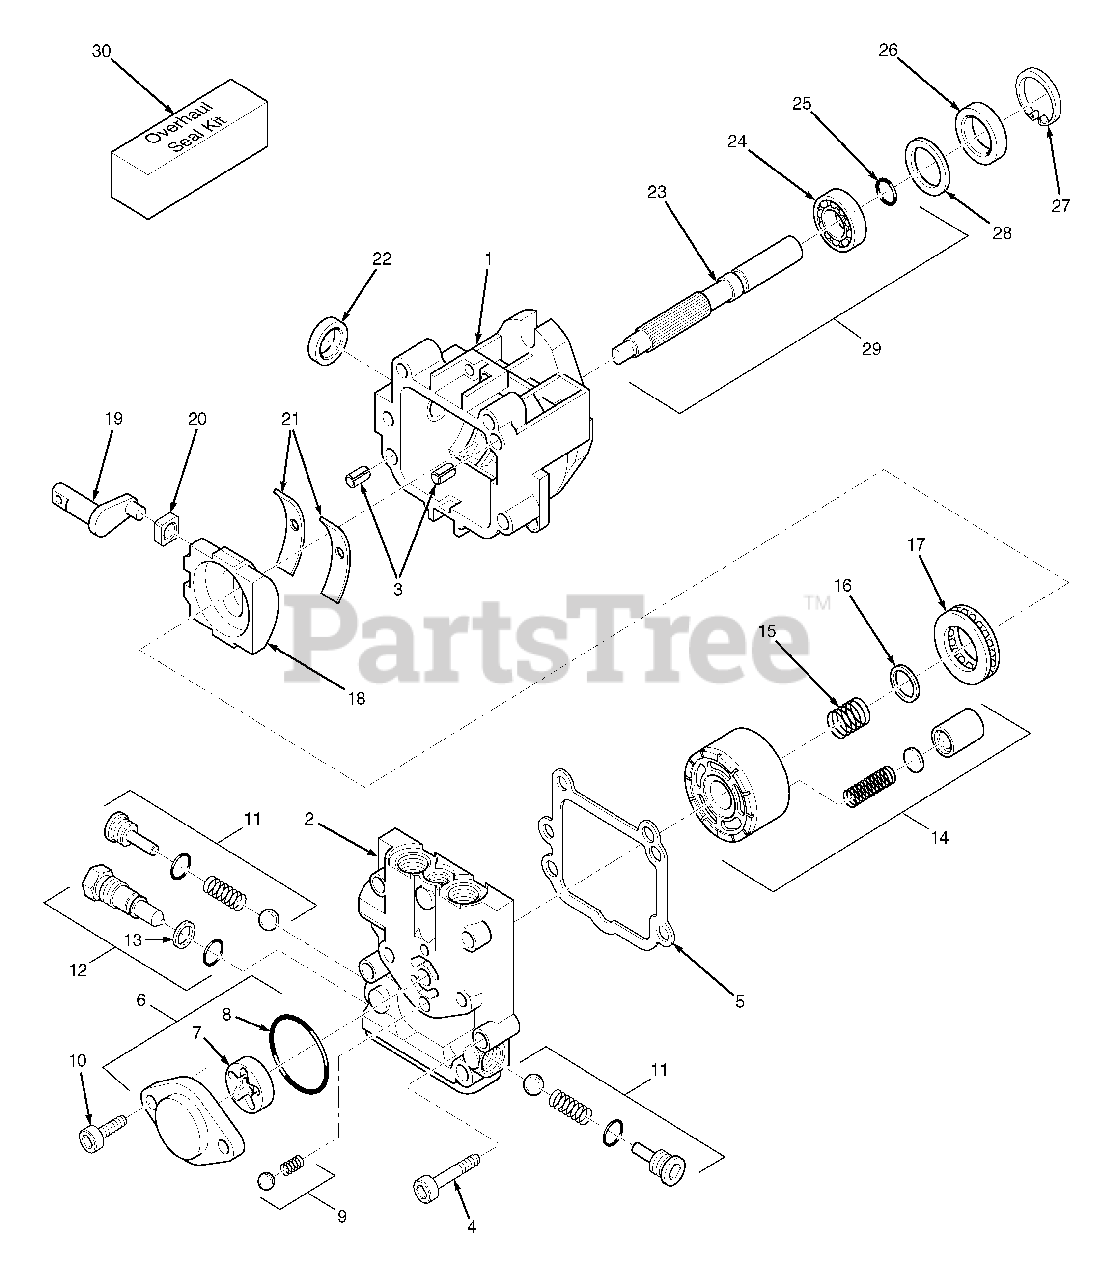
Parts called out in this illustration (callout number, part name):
1	Housing Kit
2	End Cap
3	Straight Headless Pin
4	Socket Head Screw
5	End Cap Gasket
6	Charge Pump Kit
7	Gerotor Assembly
9	Charge Relief Valve Kit
10	Socket Head Screw
11	Check Valve Kit
12	Bypass Valve Kit
13	Backup Ring
14	Cylinder Block Kit
15	Block Spring
16	Block Thrust Washer
17	Roller Thrust Bearing
18	Swash Plate
19	Trunnion Arm
20	Guide Slot
21	Cradle Bearing
23	Pump Shaft
24	Ball Bearing
25	Retaining Ring
27	Retaining Ring
29	Shaft Kit
30	Overhaul Seal Kit
